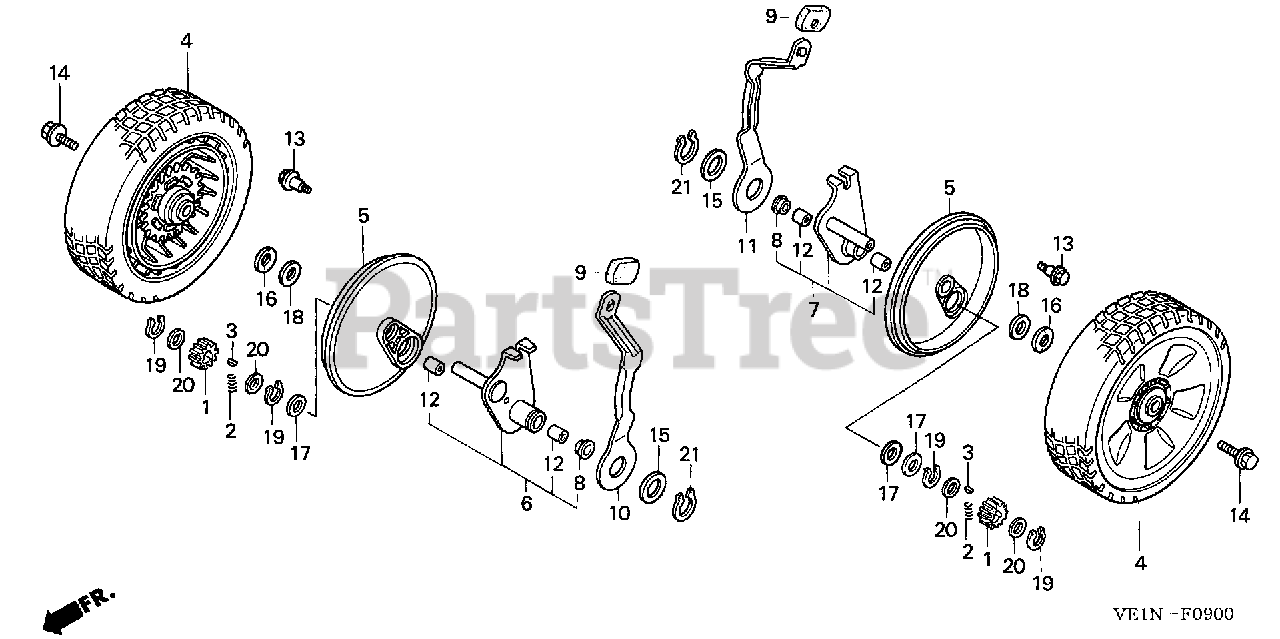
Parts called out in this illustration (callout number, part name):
1	GEAR, PINION (12T)
2	SPRING, RATCHET RETURN
3	KEY, RATCHET
4	WHEEL, RR.
6	ARM, R. RR. ADJUSTING
7	ARM, L. RR. ADJUSTING
8	DUST SEAL (12.7MM)
9	GRIP, ADJUSTER
10	PLATE, R. RR. ADJUSTER
11	PLATE, L. RR. ADJUSTER
12	BUSH, DRIVESHAFT
13	SCREW, TAPPING (5X12)
14	BOLT, WHEEL
15	WASHER, PLAIN (22MM)
16	WASHER, WHEEL
17	WASHER, THRUST (13MM)
18	WASHER, THRUST (13X27X1)
19	CIRCLIP (OUTER) (12.7MM)
20	COLLAR, PINION GEAR
21	CIRCLIP (OUTER) (22MM)
